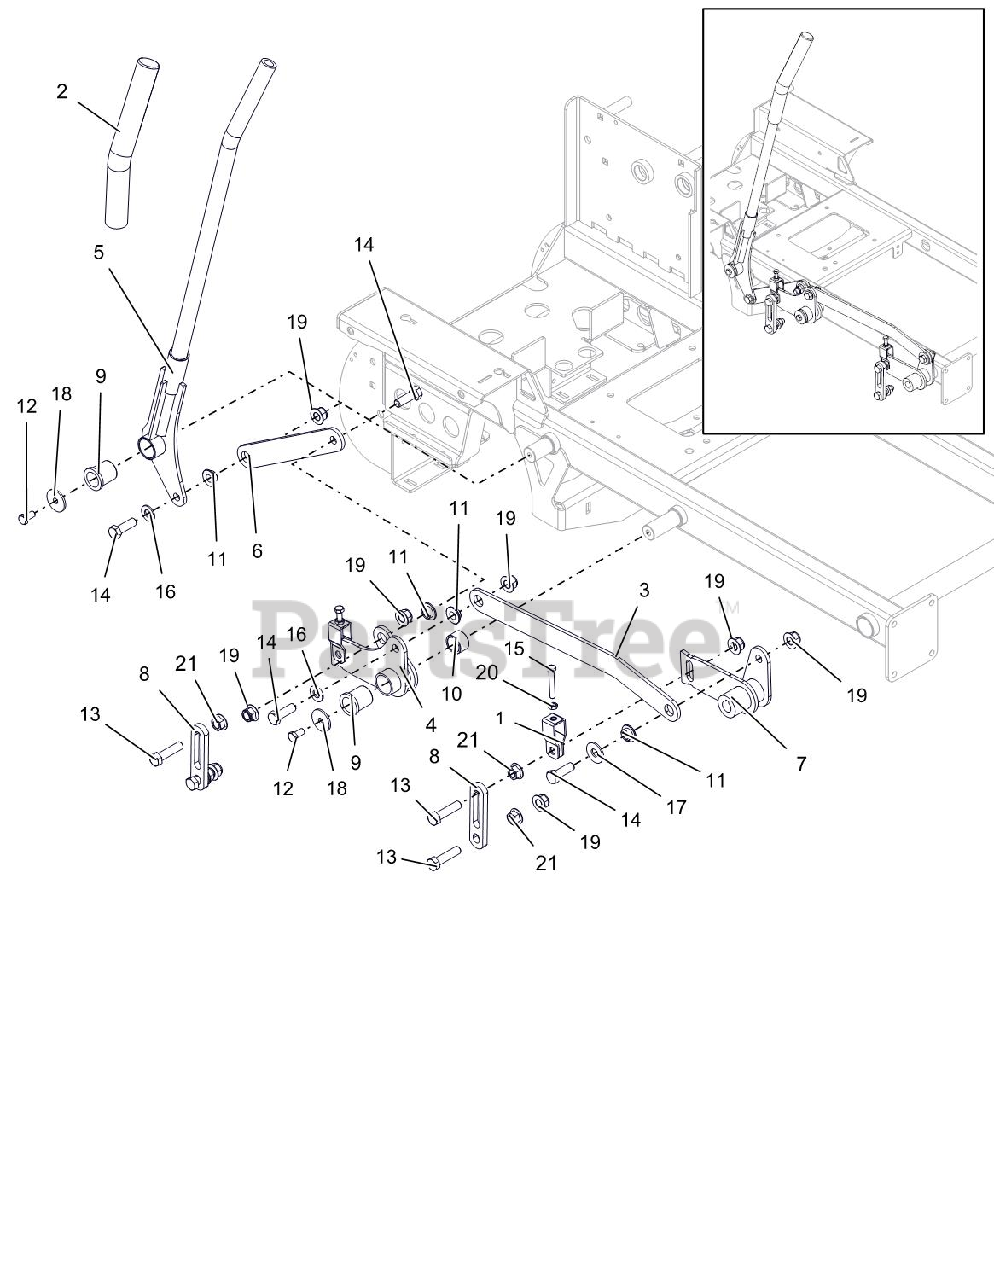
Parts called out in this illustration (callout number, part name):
1	BRKT, DECK LEVELING
2	GRIP, HANDLEBAR 1.00X1.38X11.3
3	PLATE, DECK ARM
4	WLDMT, REAR DECK ARM
5	WLDMT, DECK LIFT HANDLE
6	LINK, DECK LIFT HANDLE
7	WLDMT, RH FRONT DECK ARM
8	LINK-DECK LIFT - SHORT
9	BSHG-FLG 1.00X1.25X1.50X1.50
10	BUSH, SLV 1.00 X 1.25 X .75
11	BSHG, FLG .515X.750X.360X1.12
12	@BLT-HEX .38-16X.75 GR5 YWZC
13	@BLT-HEX .50-13X2.00 GR5 YWZC
14	@BLT-HEX .50-13X1.50 GR5 YWZC
15	BLT-HEX .312-18X2.00 FTH GR5YZ
16	@WSHR-FL-STL.531X1.06X.095YWZC
17	@WSHR-FL-STL.563X1.38X.109YWZC
18	WSHR-FL-STL .380X1.50X.125YWZC
19	@NUT-LK-NYL-FLG .50-13 YWZC
20	NUT- JAM .312-18 YWZC
21	NUT-SPNLK-FLG .50-13 YWZC
